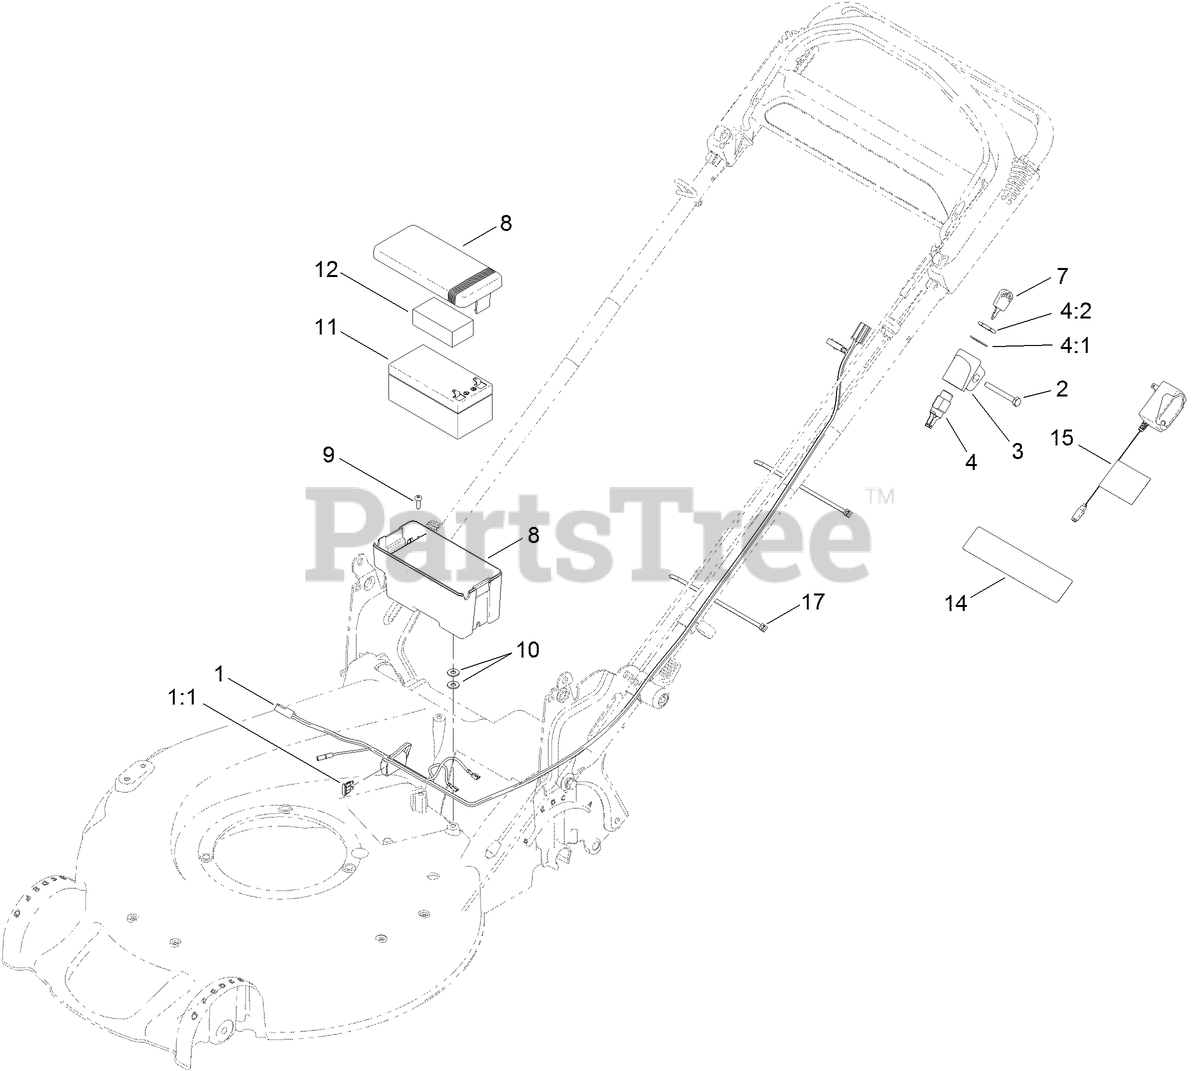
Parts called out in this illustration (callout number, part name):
1	HARNESS-WIRE
1:1	FUSE-40 AMP
2	SCREW-HH
3	MOUNT-SWITCH
4	STARTER SWITCH ASM
4:1	WASHER-LOCK
4:2	NUT-HH
8	BATTERY BOX ASM
10	WASHER-FLAT
11	BATTERY-WET
12	FOAM-BATTERY, TOP
14	DECAL-WARNING
17	TIE-CABLE
